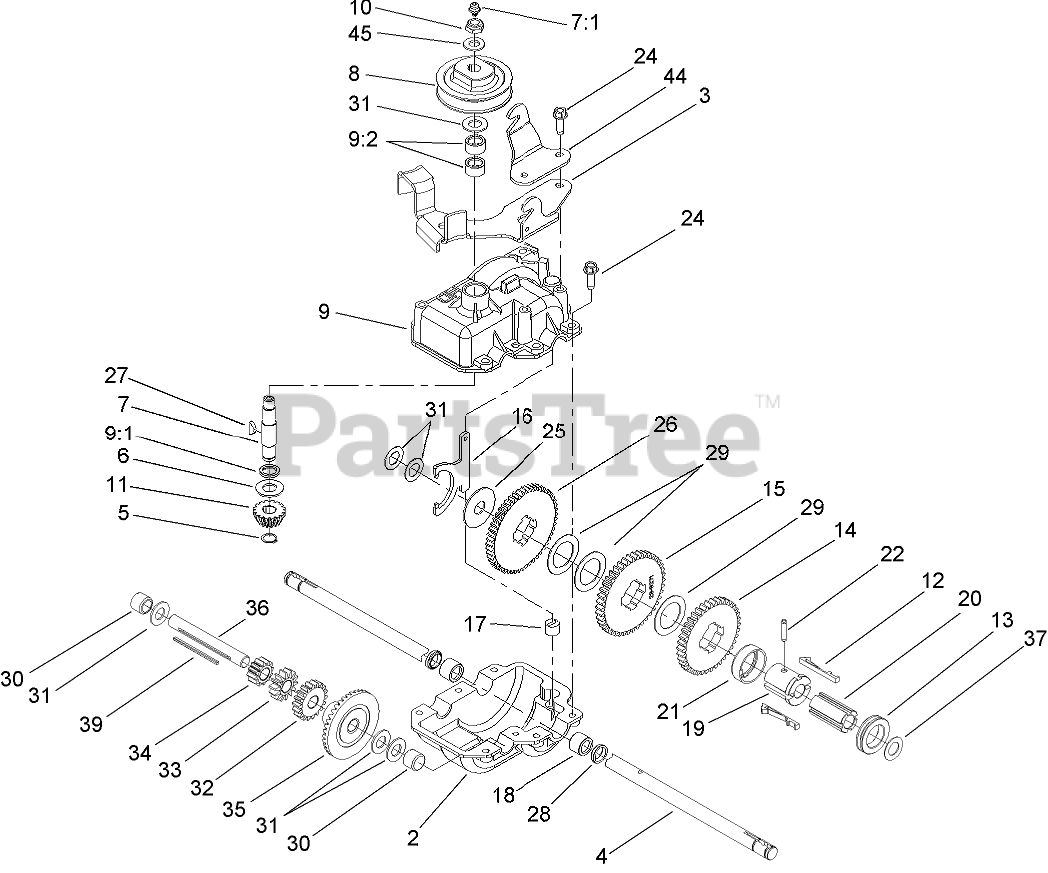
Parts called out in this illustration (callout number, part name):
2	CASE-GEAR, LOWER
3	BRACKET-GUIDE, BELT
4	SHAFT-OUTPUT
5	RING-RETAINING
6	WASHER-THRUST
7	INPUT SHAFT ASM
7:1	FITTING-GREASE, ZERK
8	PULLEY
9	UPPER GEARCASE ASM
9:2	BEARING-NEEDLE
10	NUT-HEX
11	PINION-BEVEL
12	KEY-SHIFT
13	COLLAR-SHIFT
14	GEAR-38T
15	GEAR-42T
16	YOKE-SHIFT
17	BUSHING-YOKE
18	SEAL-OIL
19	SLEEVE-GEAR
20	SLEEVE
21	RETAINER-KEY
22	PIN-GROOVE
24	SCREW-HWHTF
25	WASHER
27	KEY-WOODRUFF
28	BEARING-ROLLER
29	WASHER
30	BEARING-NEEDLE, CLOSED
31	WASHER-THRUST
32	GEAR-18T
33	GEAR-14T
34	GEAR-12T
35	GEAR-BEVEL
36	SHAFT-INTERMEDIATE
37	WASHER-PLAIN
44	BRACKET-ENGAGE, TRACTION
45	WASHER-FLAT
